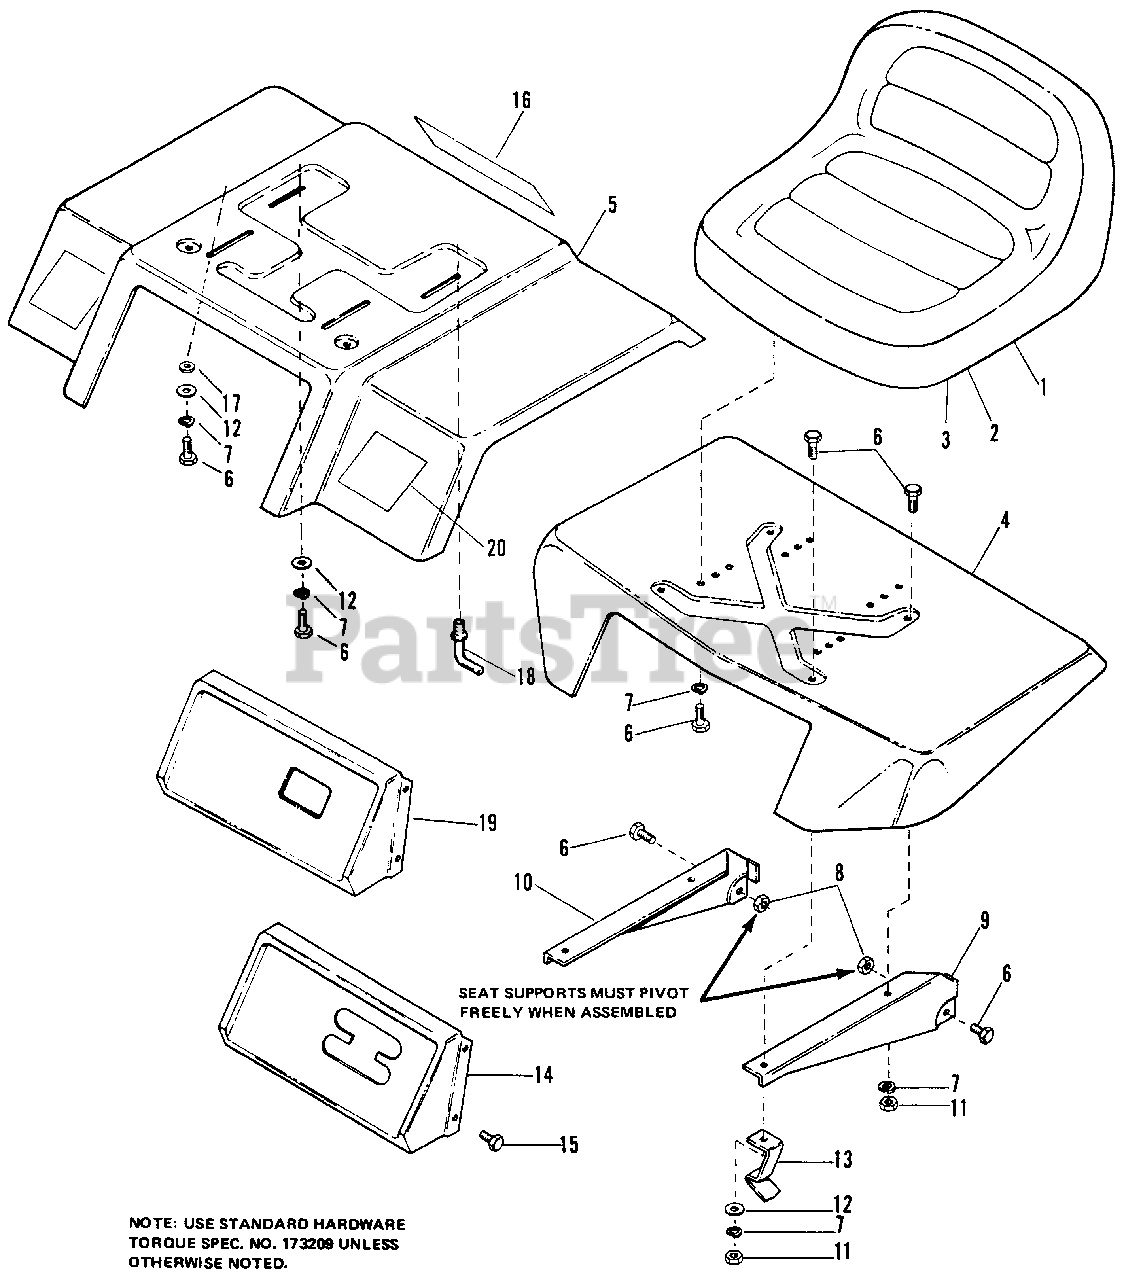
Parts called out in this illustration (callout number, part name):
1	SEAT, (Medium Back) (4108)
2	SEAT, (Low Back) (4008)
3	SEAT, (High Back) (4208)
4	SEAT DECK (4008)
5	SEAT DECK, W/Fenders (4108, 4208)
6	* CAPSCERW, 5/16-18 x 3/4
7	LOCKWASHER, 5/16
8	LOCKNUT, 5/16-18
9	SUPPORT, Seat, L.H.
10	SUPPORT, Seat, R.H.
11	NUT, Hex 5/16-18
12	WASHER, 5/16, Plain
13	LATCH, Seat
14	PANEL, Shift (4008, 4108)
15	SCREW, Taptite, 1/4-20 x 1/2
16	DECAL, Simplicity
17	SPACER, (4108)
18	SCREW-HAND, (4208)
19	PANEL, Shift, (4208)
20	DECAL, "S"
